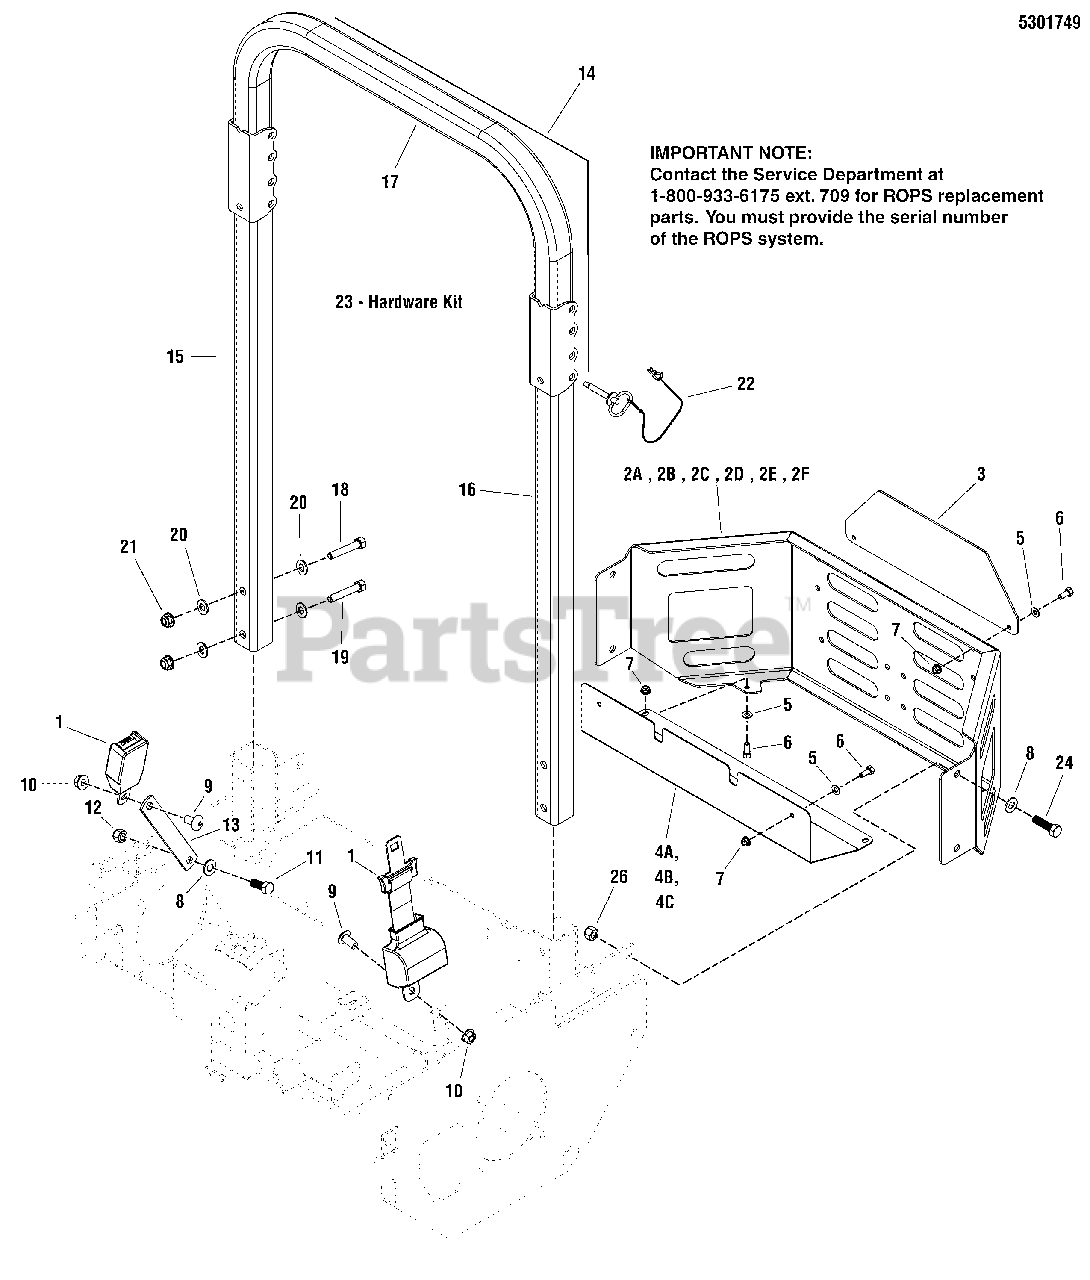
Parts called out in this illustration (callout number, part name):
1	SEAT BELT, RETRACTING - ASSM
3	PLATE, REAR BUMPER, 61 SNP - SNP RED
5	WASHER, 5/16" SAE
6	BOLT, 5/16-18 X 3/4 GD5
7	NUT, 5/16-18 HEX NYLOCK FLANGE
8	WASHER, 1/2 SAE
9	SCREW, 1/2-13 X 1.00, SHCS
10	NUT, Hex Flange, Nylock, 1/2-13
11	BOLT, 1/2-13 X 1-1/4 GD5 CZ
12	NUT, 1/2-13 HEX NYLON LOCK
13	PLATE, SEAT BELT ANCHOR - BLK
14	ROPS (Call 1-800-933-6175 ext. 2193 if replacing a ROPS)
15	ROLL BAR POST, RH (SV)
16	ROLL BAR POST, LH (SV)
17	ROLL BAR TOP LOOP (SV)
18	BOLT, 1/2-13 X 3-1/4, HEX HD, GD5, CZ (SV)
19	BOLT, 1/2-13 X 3-1/2, HEX HD, GD5, CZ (SV)
20	WASHER, 1/2 SAE
21	NUT, Hex Flange, Nylock, 1/2-13
22	PIN, HITCH, .50 X 3.25 W/ LAY (SV)
23	HARDWARE KIT, ROPS (SV)
24	BOLT, 1/2-13 X 1-1/2 GD5 CZ
